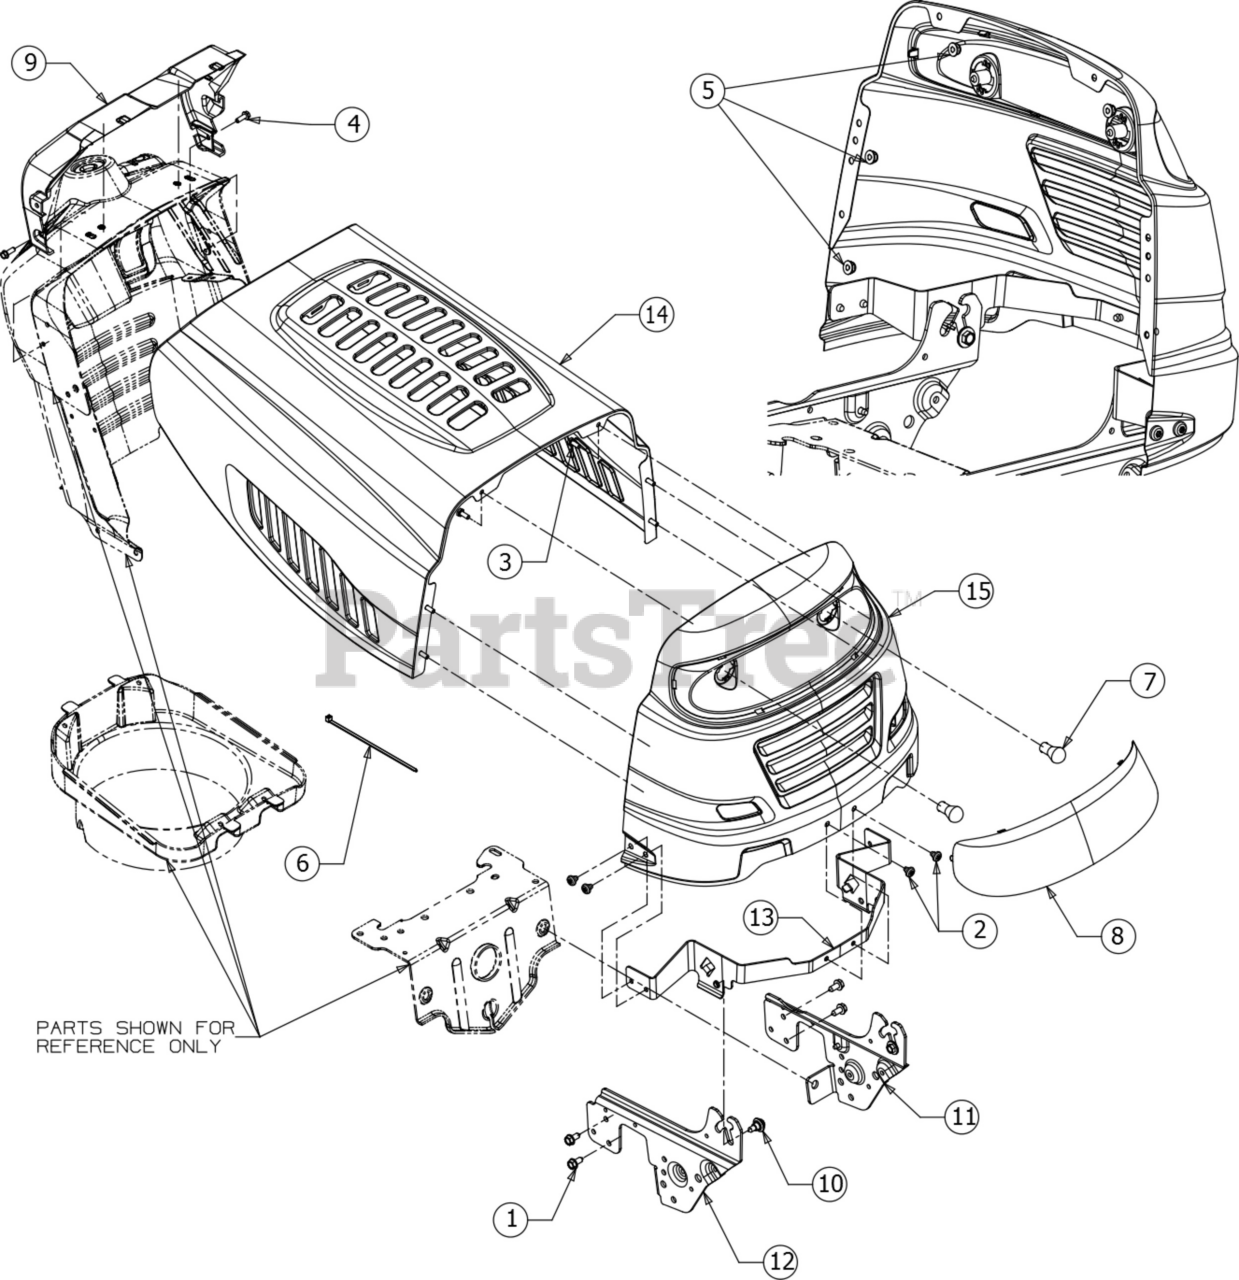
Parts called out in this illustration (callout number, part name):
1	SCREW 5/16-18 x .750
2	SCREW 5/16-18 X .375
3	SCREW 1/4-20 x .620 GR5
4	SCREW 1/4-15 X .750
5	FLANGE LOCK NUT
6	CABLE TIE 7"
7	MINIATUURE BULB 12V
8	GRILL LENS
9	DASH COLLAR
10	SHOULDER SCREW .43X.29X5/16-18 TT
11	SUPPORT BRACKET (LH)
12	SUPPORT BRACKET (RH)
13	HOOD PIVOT BRACKET
